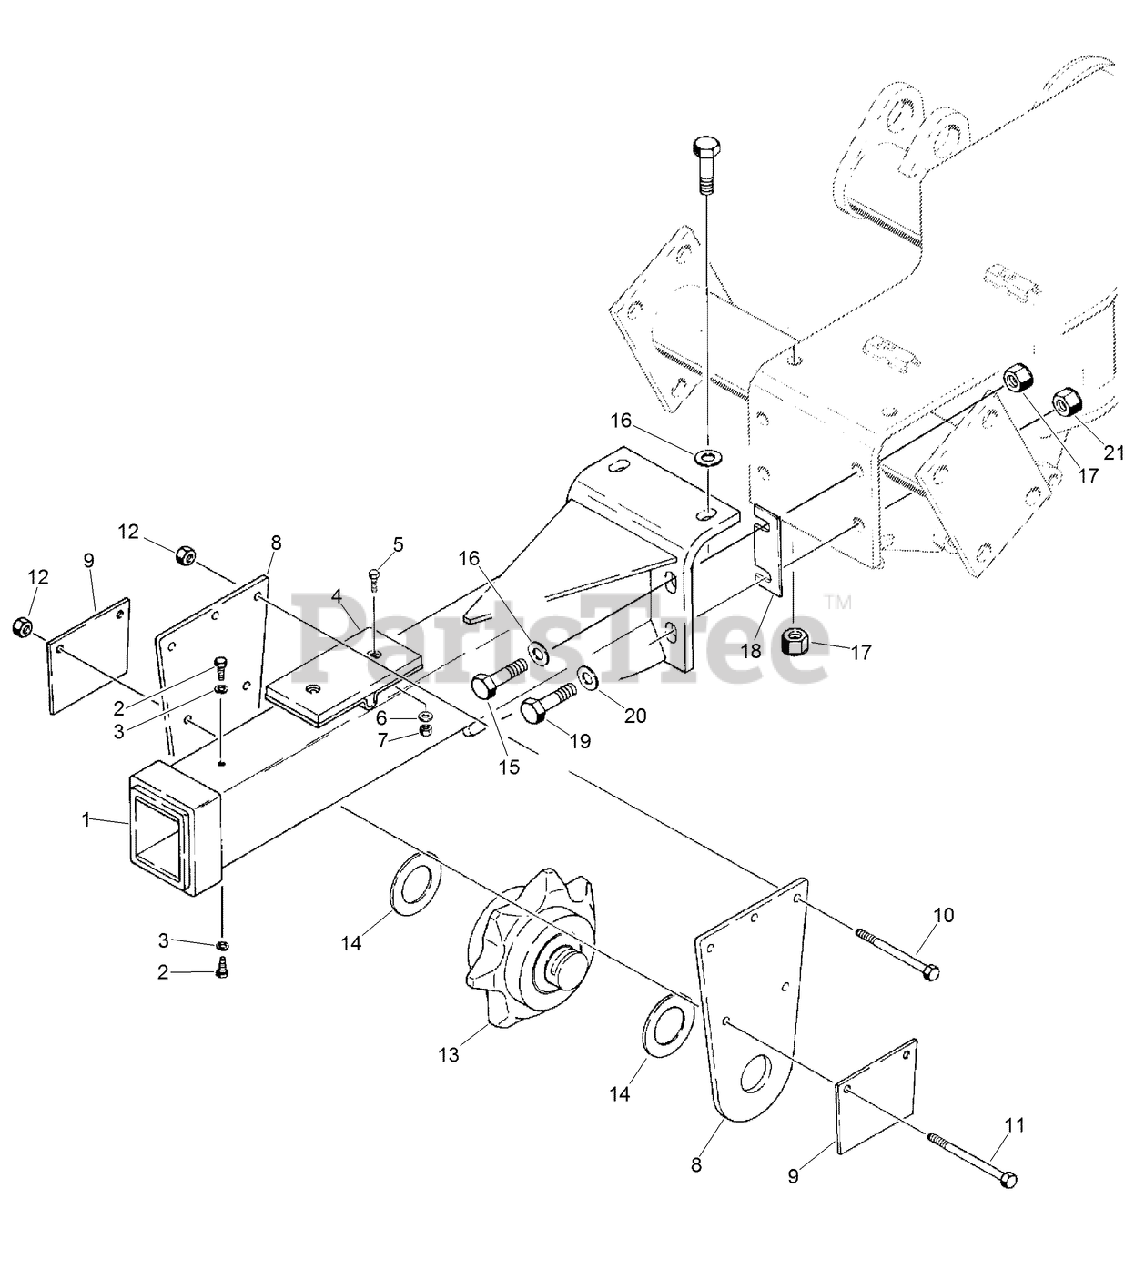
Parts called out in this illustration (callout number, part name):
1	BOOM - 4 Ft (Uses 1 Idler Sprocket) (If used)
1	BOOM - 5 Ft (Uses 1 Idler Sprocket) (If used)
1	BOOM - 6 Ft (Uses 2 Idler Sprockets) (If used)
1	BOOM - 7 Ft (Uses 2 Idler Sprockets) (If used)
2	SCREW - Self-Tapping, 5/16 ST x 3/4
3	WASHER-Lock, 5/16 inch
4	PAD - Wear
6	WASHER-Flat
7	NUT-HEX FLANGE
8	PLATE - Idler Sprocket
9	RETAINER
10	BOLT - 1/2 x 5-1/4
11	BOLT - 1/2 x 5-3/4
12	NUT-LOCK, HEX
13	SPROCKET - Idler, 311 Chain
13	SPROCKET - Idler, 408 Chain
14	WASHER - Lock, 5/16
